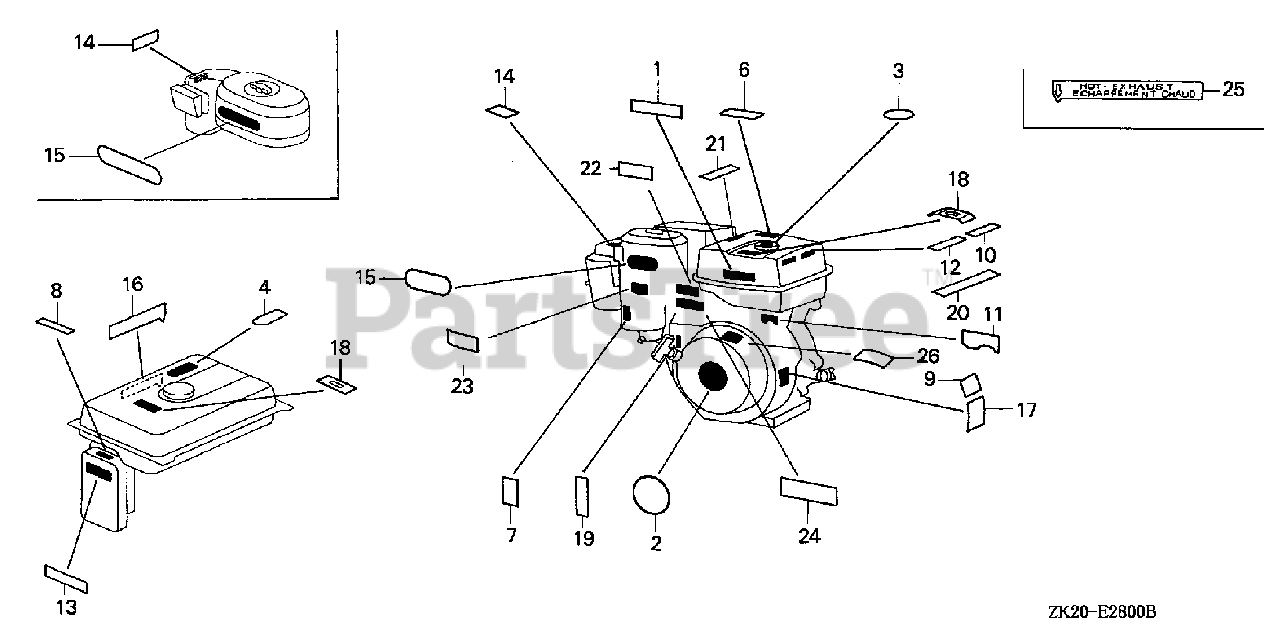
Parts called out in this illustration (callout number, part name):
1	LABEL, CAUTION
2	EMBLEM (INTERNAL)
2	EMBLEM
7	MARK, CHOKE (EXTERNAL)
12	MARK, OIL ALERT (E)
19	MARK, OIL ALERT (FRENCH)
20	MARK, OIL ALERT (GERMAN)
